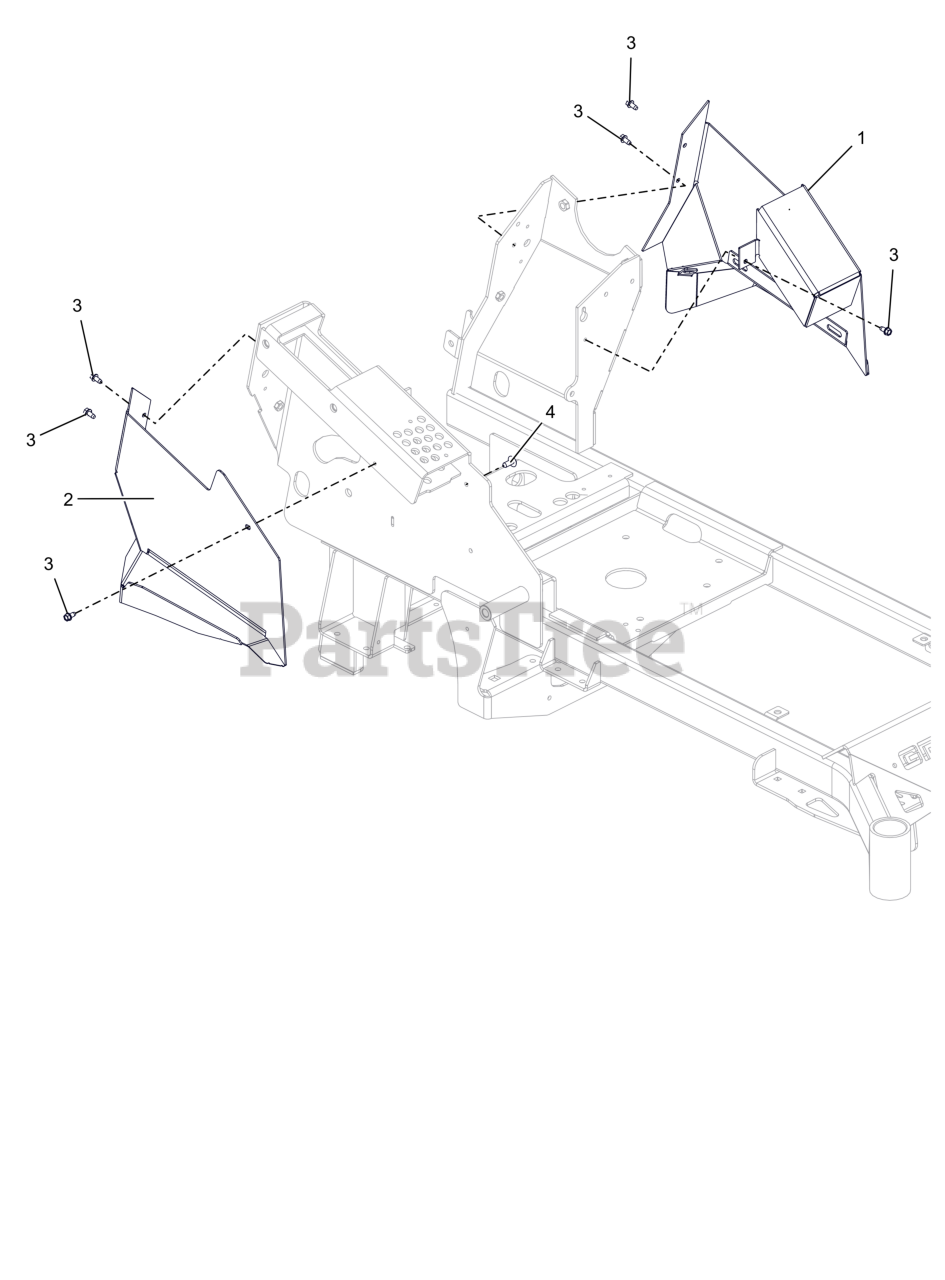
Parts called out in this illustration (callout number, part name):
1	WLDMT, LH FENDER (BLACK)
2	WLDMT, RH 32-36" FENDER (BLACK)
3	SCR-TAP .25-20X.50 HWH ZCC
4	XMAS TREE FASTNER-BLACK
